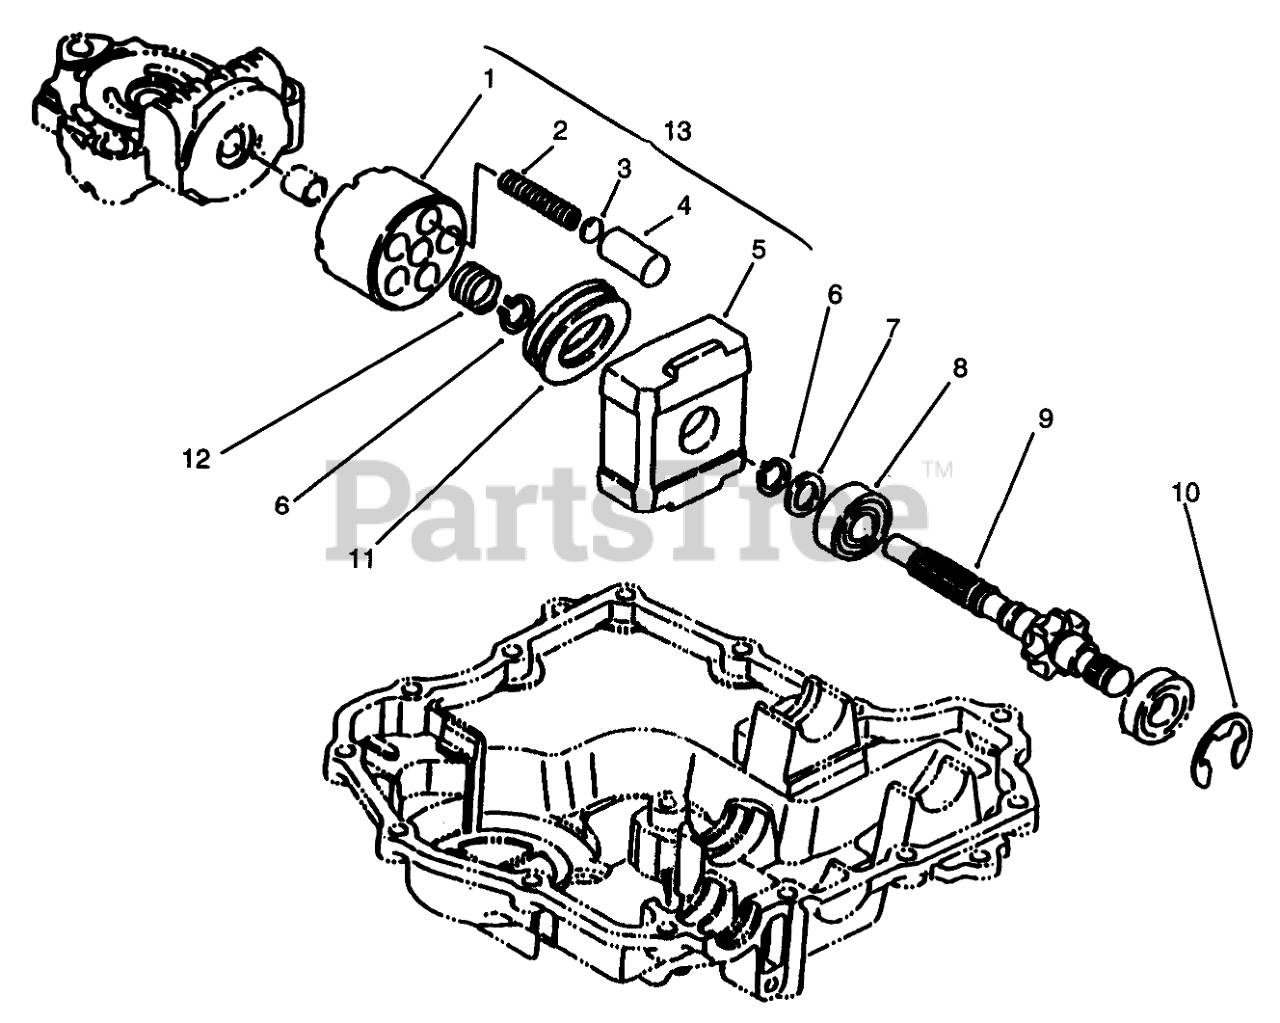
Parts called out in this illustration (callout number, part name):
5	Housing (Only On: 72043, 72063, 72103)
6	Ring-Snap (Only On: 72043, 72063, 72103)
7	Washer (Only On: 72043, 72063, 72103)
8	Bearing-Ball (Only On: 72043, 72063, 72103)
9	Shaft-Motor (Only On: 72043, 72063, 72103)
10	E Ring (Only On: 72043, 72063, 72103)
11	Bearing-Thrust (Only On: 72043, 72063, 72103)
13	Cylinder ASM INCL 1-4 (Only On: 72043, 72063, 72103)
